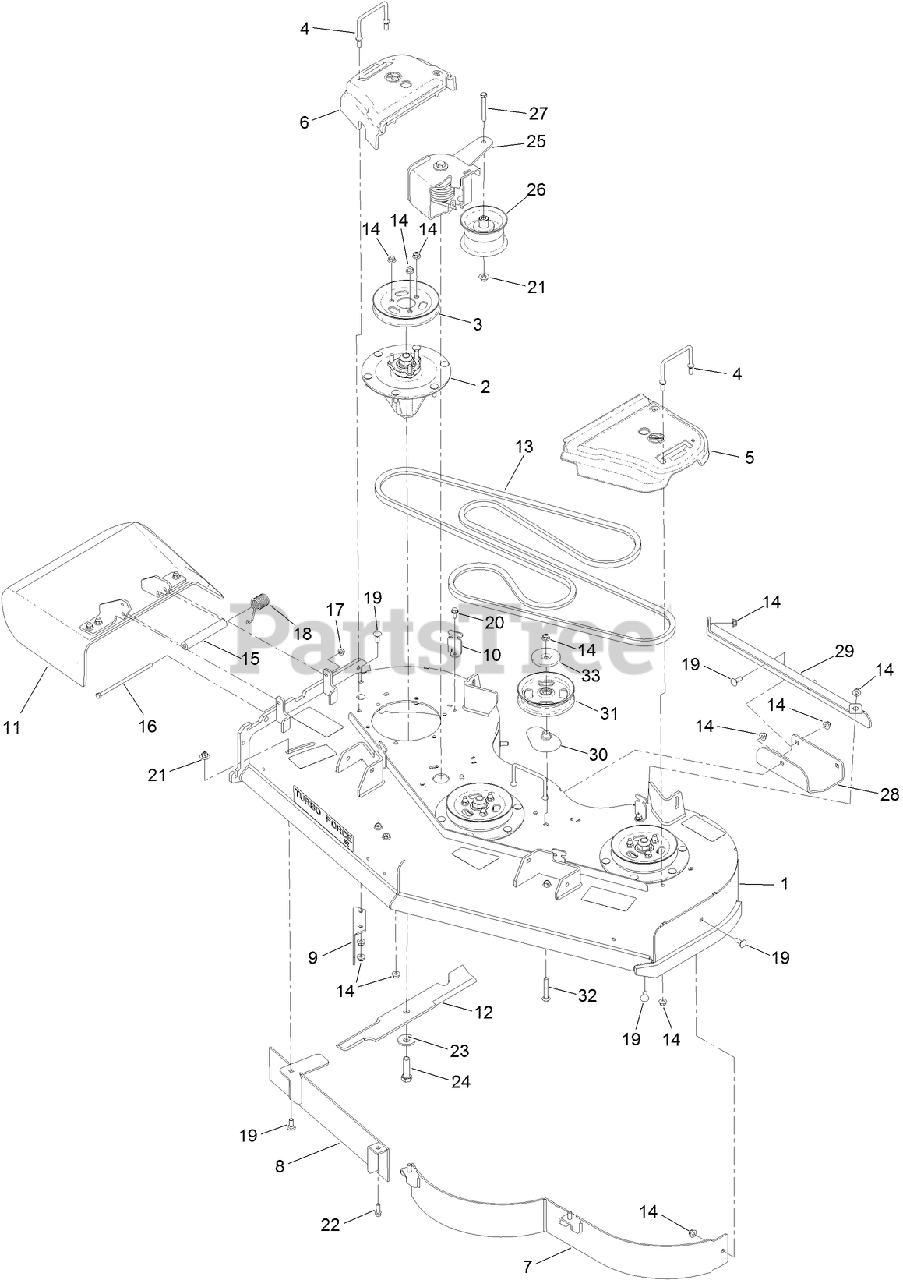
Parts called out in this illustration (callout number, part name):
1	DECK ASM
2	SPINDLE ASM
3	PULLEY
4	WIREFORM-COVER
5	COVER-BELT, LH
6	COVER-BELT, RH
7	BAFFLE-52 INCH
9	BAFFLE-DISCHARGE
10	BRACKET-COVER
11	DEFLECTOR ASM
12	BLADE-18IN, HI FLOW
13	BELT-V
14	NUT-HF, NI
15	SPACER
16	SCREW-HH
17	NUT-HF, NI
18	SPRING-TORSION
19	SCREW-HH
20	SCREW-HWHTF
21	NUT-FLANGE, NI
23	WASHER-BLADE BOLT, HEAVY
24	SCREW-BLADE
25	IDLER TORSION ASM
26	PULLEY-IDLER
27	SCREW-HH
29	BRACKET-SKID
30	SPACER-PULLEY
31	PULLEY-IDLER,FLAT
32	SCREW-CARR
33	SHIELD-DUST
